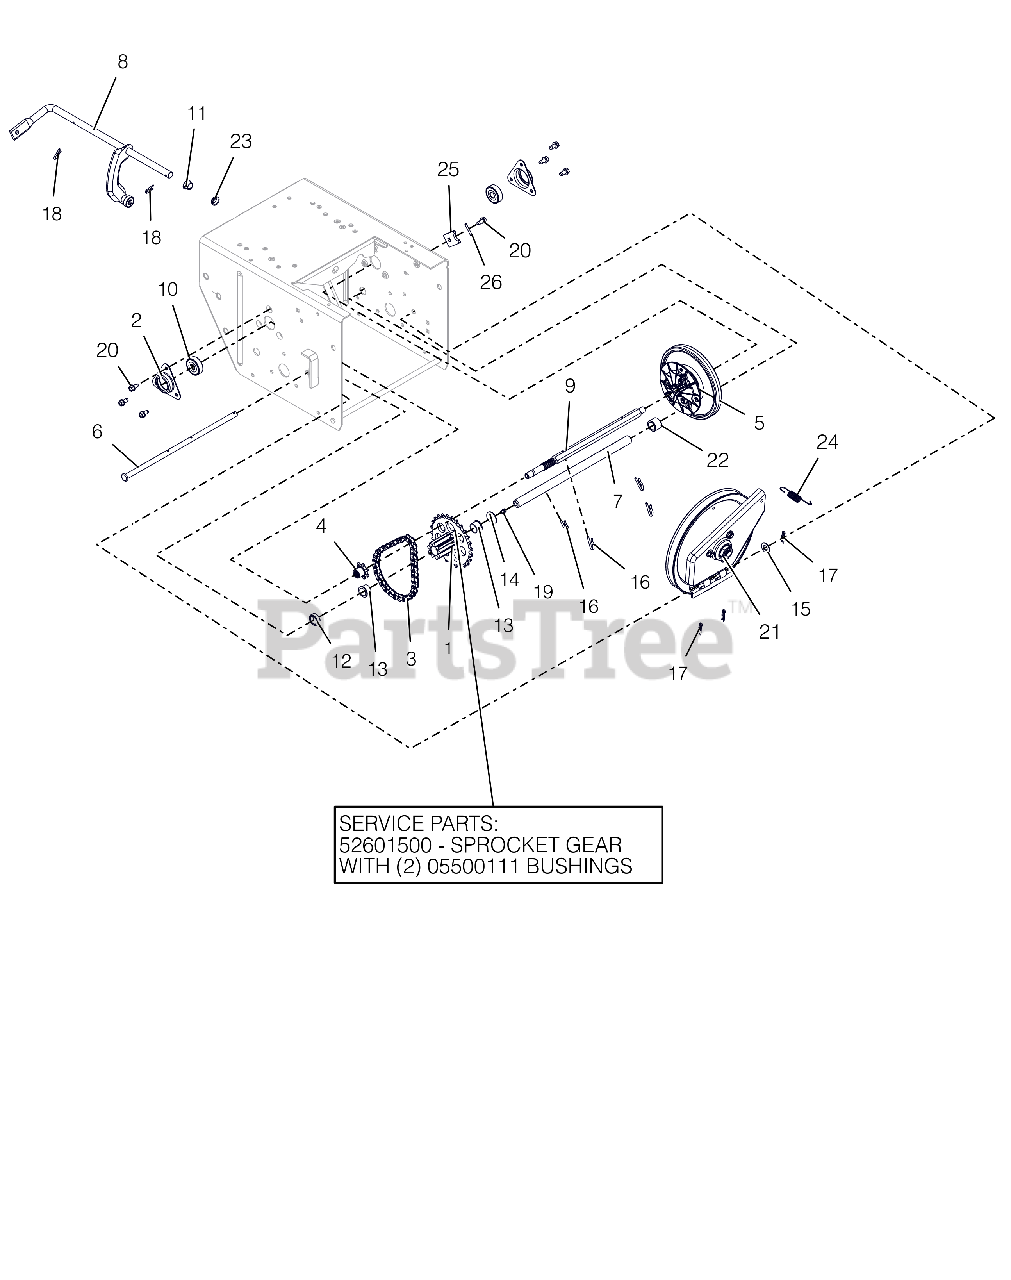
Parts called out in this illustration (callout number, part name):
1	PINION & SPROCKET
1	PINION & SPROCKET W/BUSHINGS
1	BSHG-FLG .625X.750X.500X.875
2	FLANGE, BEARING
3	CHAIN - #41, 32 PITCHES
4	SPROCKET, PINION 7T W/SPLINE
5	DISC, FRICTION DRIVE-ASSEMBLY
6	PIN, PIVOT
7	SHAFT, PINION - HARDENED
8	ARM, SHIFT-PRO (ASSEMBLY)
9	SHAFT, HEX - HEAT TREATED
10	BRG-BALL .437X1.375X.437
11	BUSHING, POLYLINER-.50 SPLIT
12	BSHG-SLV, .635X.880X.305
13	BSHG-FLG .625X.750X.500X.875
14	WSHR-FL-STL .630X1.005X.062 YZ
15	@WSHR-FL-STL.406X.812X.065 YWZ
16	PIN, SPRING CLIP
17	PIN-HAIR, ENDRIES #25 YWZC
18	CLIP, SPRING
19	ZERK,FITTING .25X.125 DRIVE IN
20	SCR-TAP .25-20X.50 HWH TR YWZ
21	PLATE, SWING ASSEMBLY-DEEP
22	SPACER, .635X.880X.611
23	BUSHING, POLYLINER-.50 SNAPIN
24	SG-TENS .048X.50X2.8
25	TAB, ANTI ROTATION
26	PIN-ROLL .125X1.00
